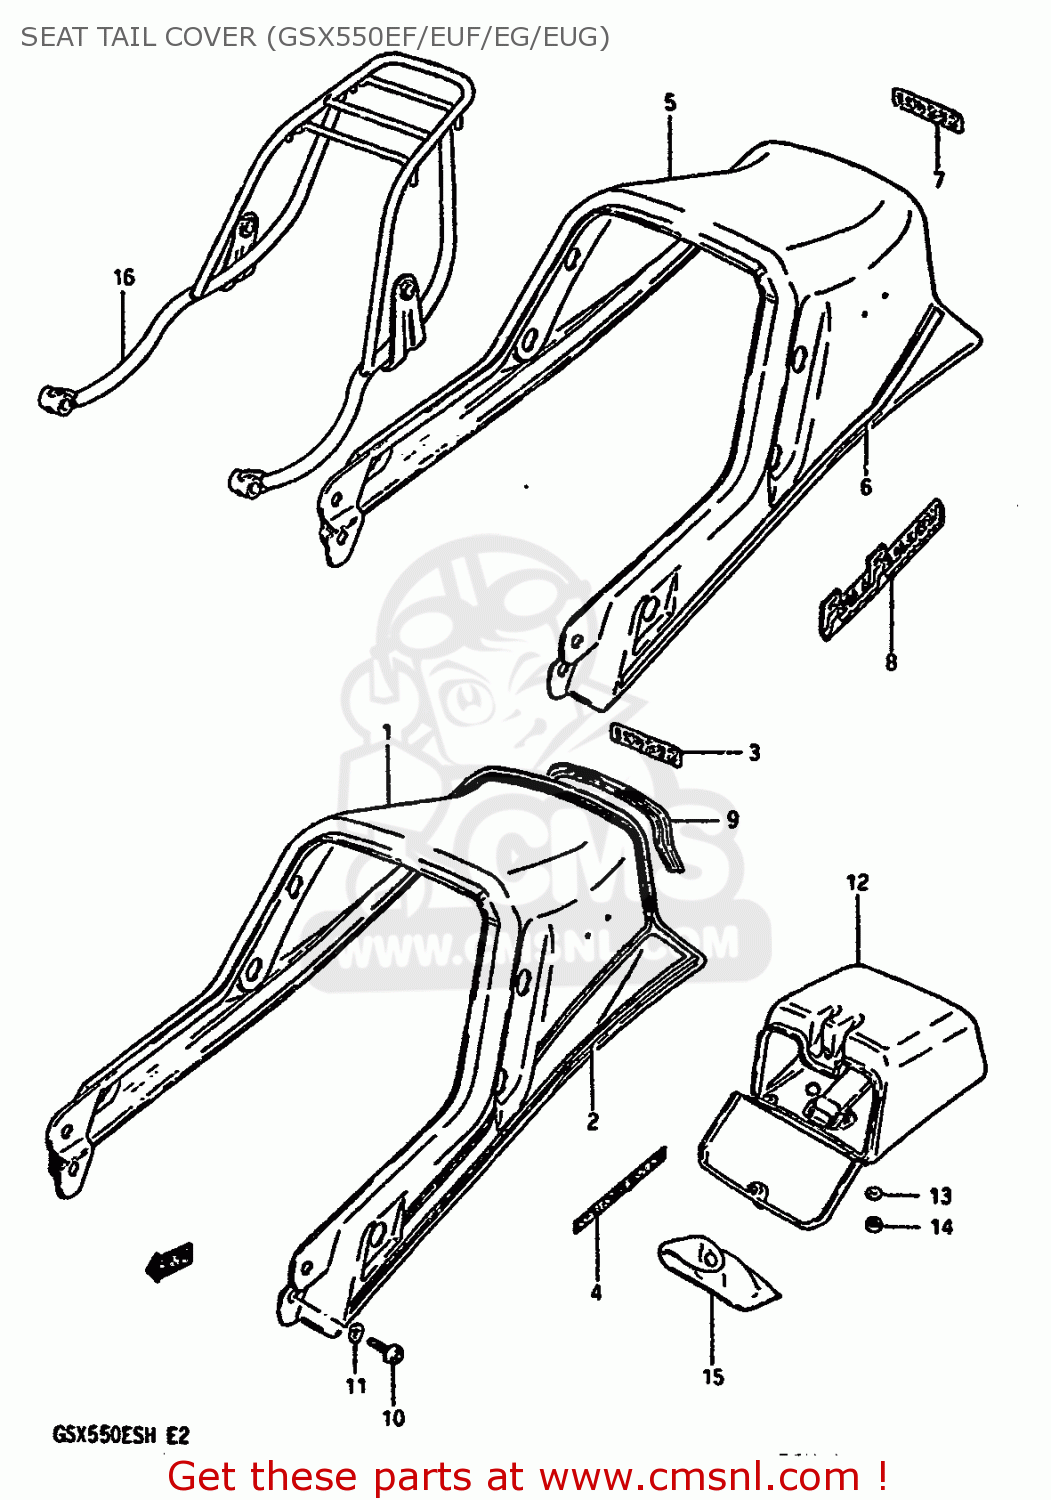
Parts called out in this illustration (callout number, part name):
1	COVER,SEAT TAIL
2	TAPE SET,SEAT TAIL COVER
3	EMBLEM(WHITE)
4	EMBLEM
5	COVER,SEAT TAIL
6	TAPE SET
7	EMBLEM(WHITE)
8	EMBLEM
9	BLIND,SEAT TAIL COVER
10	SCREW
11	WASHER,LOCK
12	BOX,SEAT TAIL
13	WASHER
14	NUT
15	TOOL ASSY
16	CARRIER, SPORTS
